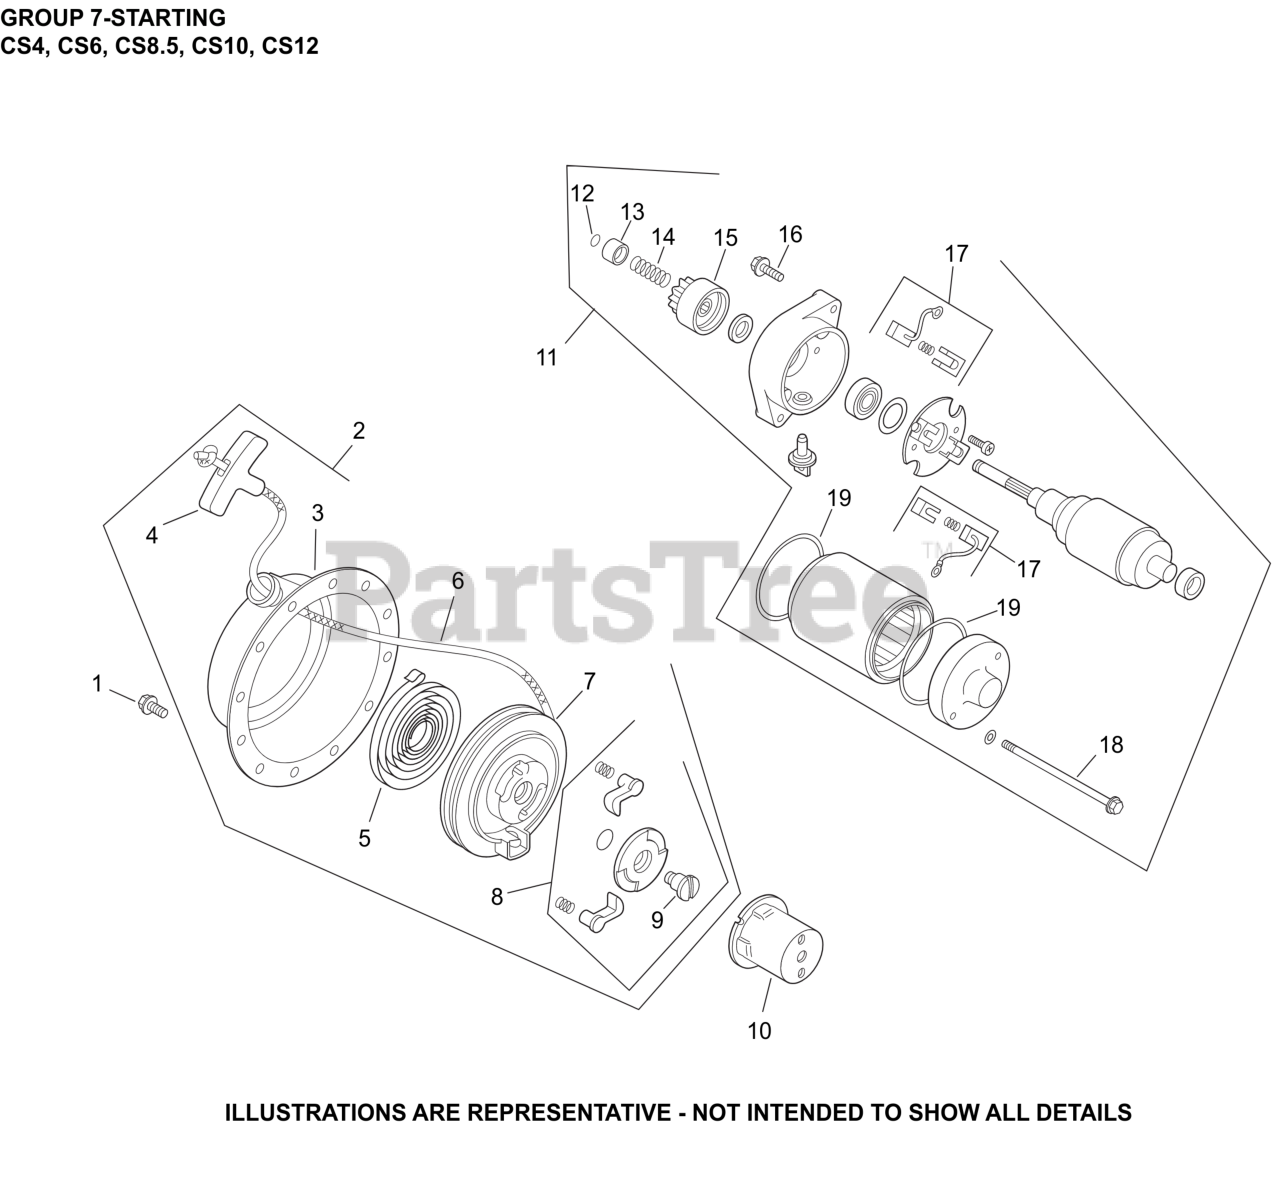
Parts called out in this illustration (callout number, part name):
1	SCREW, GUARD
4	HANDLE-(#DSC)
NI	GEAR ASSEMBLY, STARTER
NI	HOUSING ASSEMBLY
NI	SPRING, STARTER
NI	SPRING, RETURN
NI	ELECTRIC STARTER-BENDIX DRIVE
NI	CUP, DRIVE
NI	RING, STOP
NI	BUSHING, TERMINAL
NI	ROPE, STARTING
NI	RETRACTABLE STARTER
NI	BRUSH HOLDER ASSY
NI	WASHER, PLAIN
NI	STOPPER, PINION-DISCONTINUED
NI	KIT,PAWL REPAIR - CS8.5,10,12
